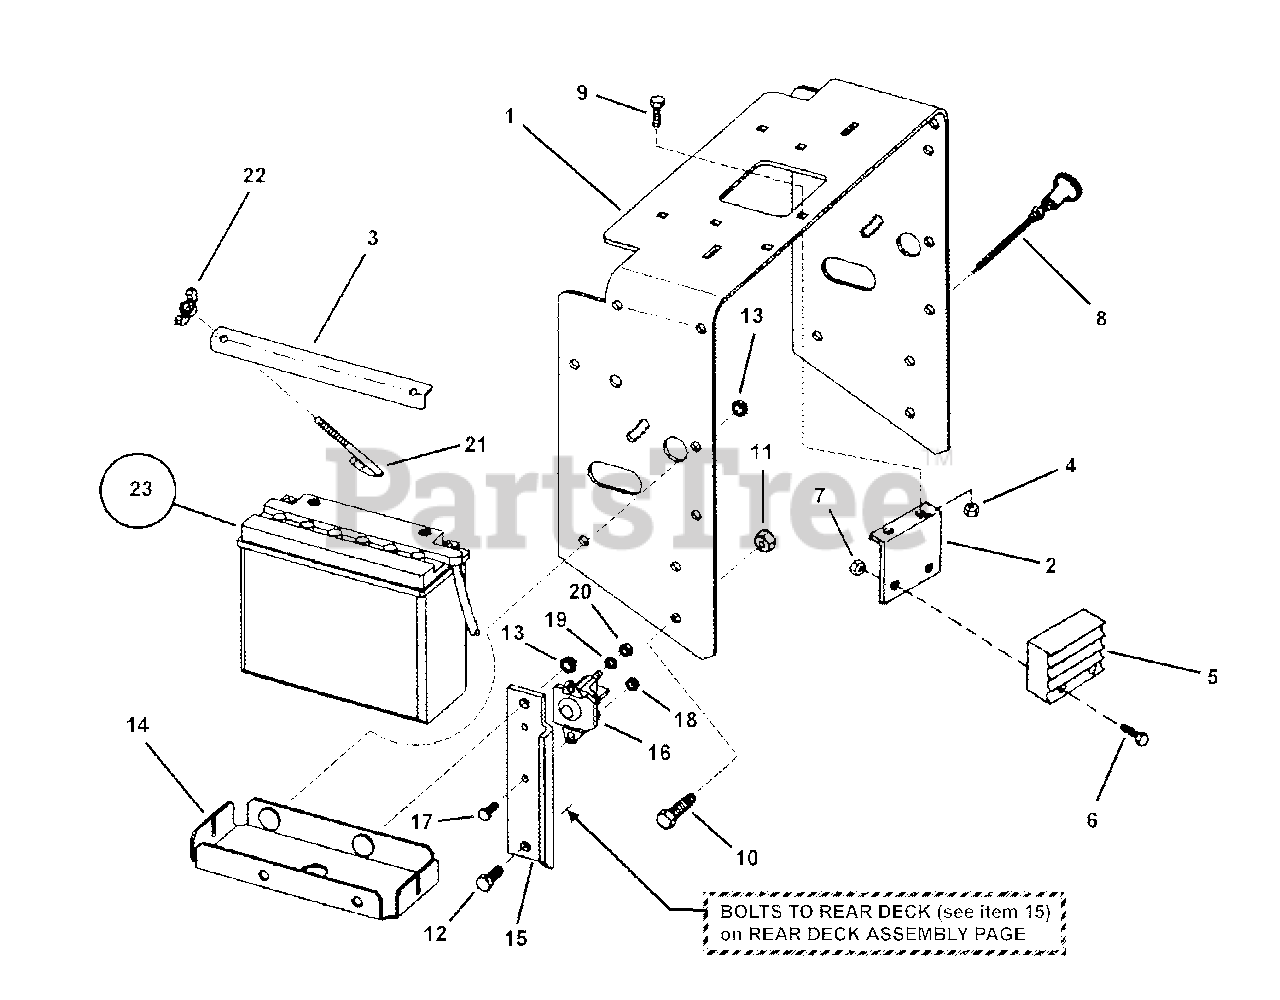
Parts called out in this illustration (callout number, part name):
1	WELDMENT, Tank Bracket- Hydro
2	BRACKET, Regulator
3	* STRAP, Battery Clamp
4	NUT, 5/16-18 HEX NYLON LOCK
5	REGULATOR/RECTIFIER (Kawaaski p/n 21066-2071)
5	REGULATOR (Kawaaski p/n 21066-2070)
6	BOLT, 1/4-20 X 1" GD5 CZ
7	NUT, 1/4-20 Hex Top Lock, GR B
8	CABLE, Choke (Incl. hardware)
9	BOLT, 5/16-18 X 1 GD5 YZ
10	BOLT, 3/8-16 X 1" GD5 CZ
11	NUT, 3/8-16 HEX NYLON LOCK
12	BOLT, 3/8-16 X 1" GD5 CZ
13	NUT, 3/8-16, HEX TOP LOCK
14	* TRAY, Battery
15	* BRACE, Battery
16	* SOLENOID, 12 Volt
17	SCREW, 1/4-20 x 3/4" Hex Head Cap, GR 5
18	NUT, 1/4-20 Hex Top Lock, GR B
19	* WASHER, 1/4" Internal Tooth lock
20	* NUT, 1/4-20 Hex, GR 5 or B
21	* J-BOLT, 1/4-20 thread
22	* NUT, 1/4-20 Wing
23	* KIT, Battery
